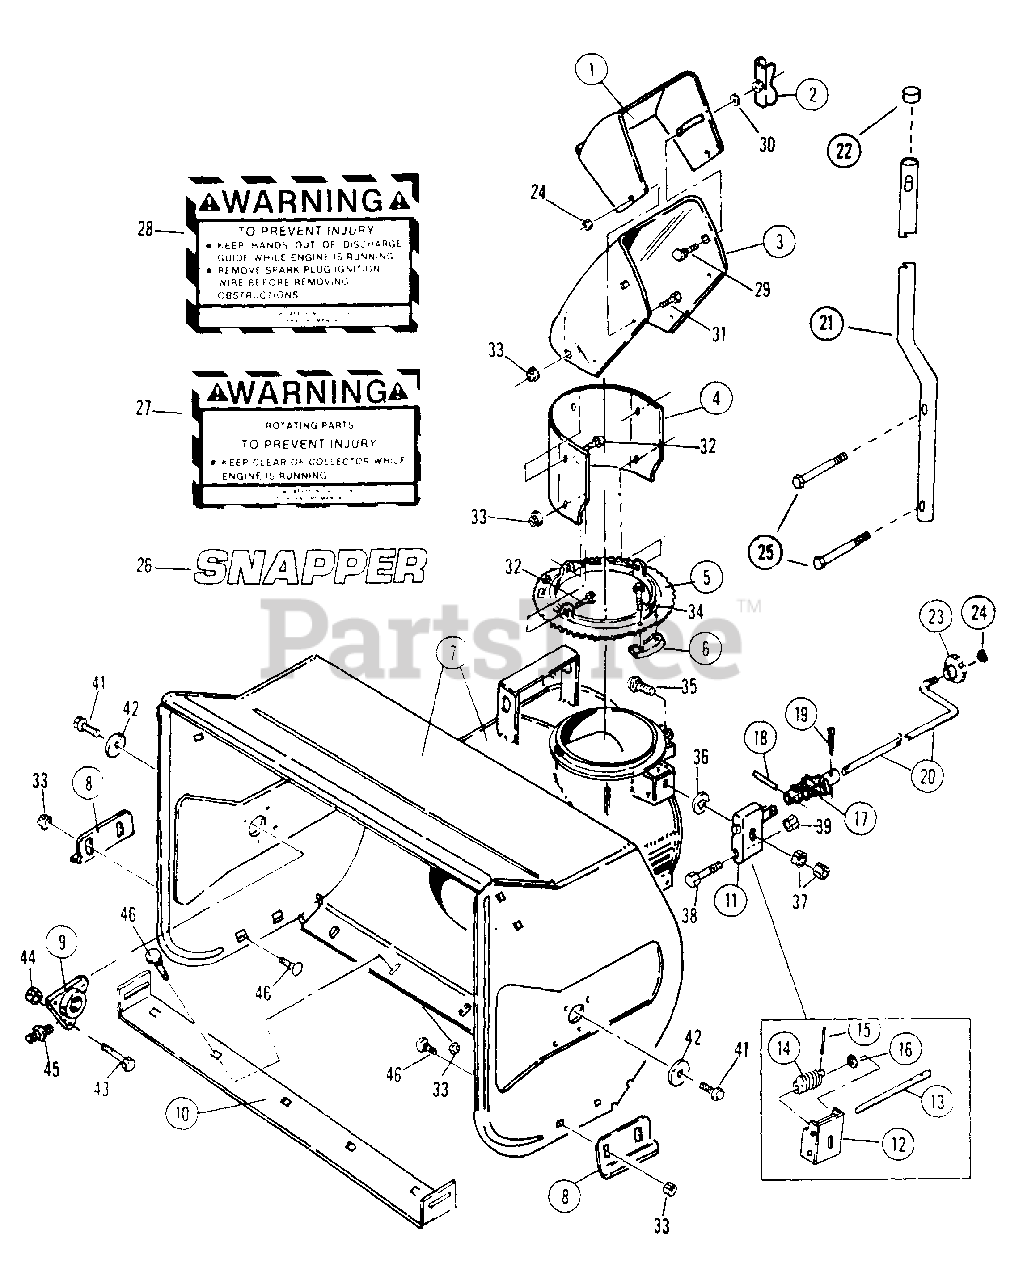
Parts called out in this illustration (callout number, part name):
1	DEFLECTOR
2	WING-NUT
3	CHUTE ASSEMBLY
4	EXTENSION, Chute
5	RING, Chute
6	RETAINER, Chute Ring
7	HOUSING,Blower (36")
8	SHOE, Skid
9	BEARING, Auger Shaft
10	BLADE, Scraper
11	ASSEMBLY, Worm Bracket
12	BRACKET, Worm
13	SHAFT, Worm
14	WORM
15	ROLL-PIN, 1/8x3/4
16	WASHER, Spring Steel
17	UNIVERSAL JOINT
18	PIN, 1/8" x 1" Roll
19	COTTER-PIN, 1/8x1
20	CRANK, Chute
21	BRACE, Chute Crank
22	CAP, Crank Brace
23	KNOB, Chute Crank
24	LOCK NUT, 5/16C
25	SCREW, 5/16-18x1-1/2 Self Tap
26	DECAL, SNAPPER
27	DECAL, Collector Warning
28	DECAL, Deflector Warning
29	BOLT, 1/4Cx3/4 Carriage
30	WASHER, 1/4 SAE Flat
31	SCREW, 5/16Cx1/2, Hex Head Cap
32	BOLT, 5/16-18x1/2 Gr.5 Carriage
33	NUT, 5/16-18 Flange
34	SCREW, 10Cx1/2 Hex Hd Self Tap.
35	BOLT, 5/16Cx1 Carriage
36	RETAINER, Bolt
37	NUT, 5/16C Hex
38	SCREW, 5/16-24x2-1/2 Hex Head Cap
39	LOCK NUT, 5/16-24 Hex
41	SCREW, 3/8Cx1/2 Self Tap.
42	WASHER, 3/8" Flat
43	BOLT,1/4Cx5/8 Hex Flange Lock
44	NUT, 1/4C Hex Flange
45	FITTING, Lube (Press fit for .187 hole-no ball)
46	BOLT, 5/16-18x3/4 Carriage
